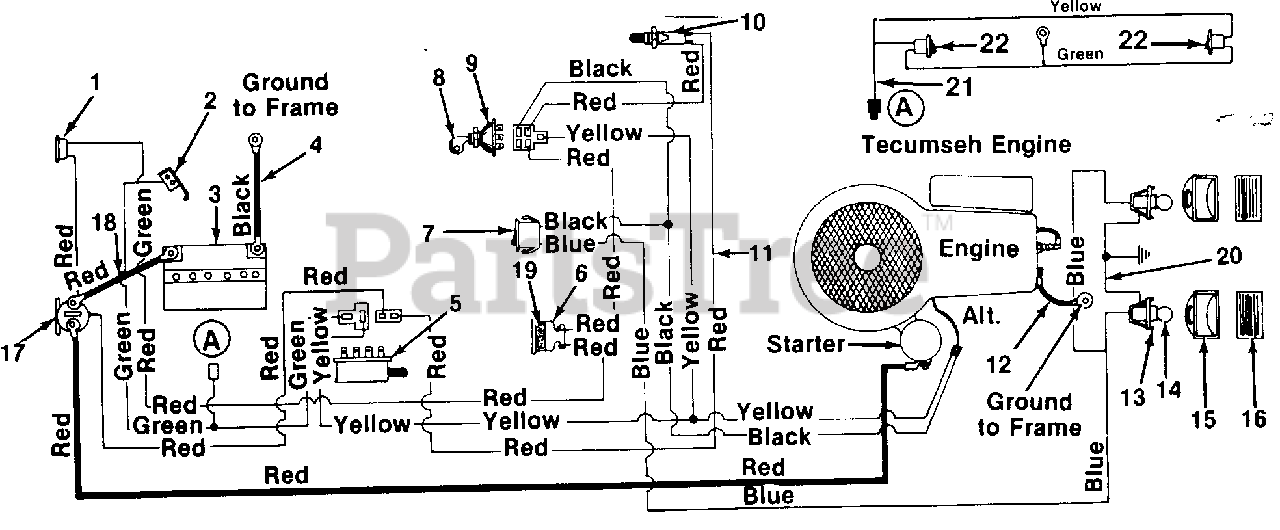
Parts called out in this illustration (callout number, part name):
1	Circuit Breaker
2	Spring Switch
3	Battery
4	Ground Wire 9.0" Lg.
5	Safety Switch
6	Ammeter
7	Light Switch
8	Ignition Key
9	Ignition Switch
10	Safety Switch
11	Wire Harness
12	Ground Wire 7.25" Lg.
13	Twist Lock Lamp Socket
14	Lamp
15	Headlight Housing
16	Lens
17	Solenoid
18	Electric Wire w/Boot
19	Foam Strip
20	Ground Wire
21	Wire Lead
22	Safety Switch
